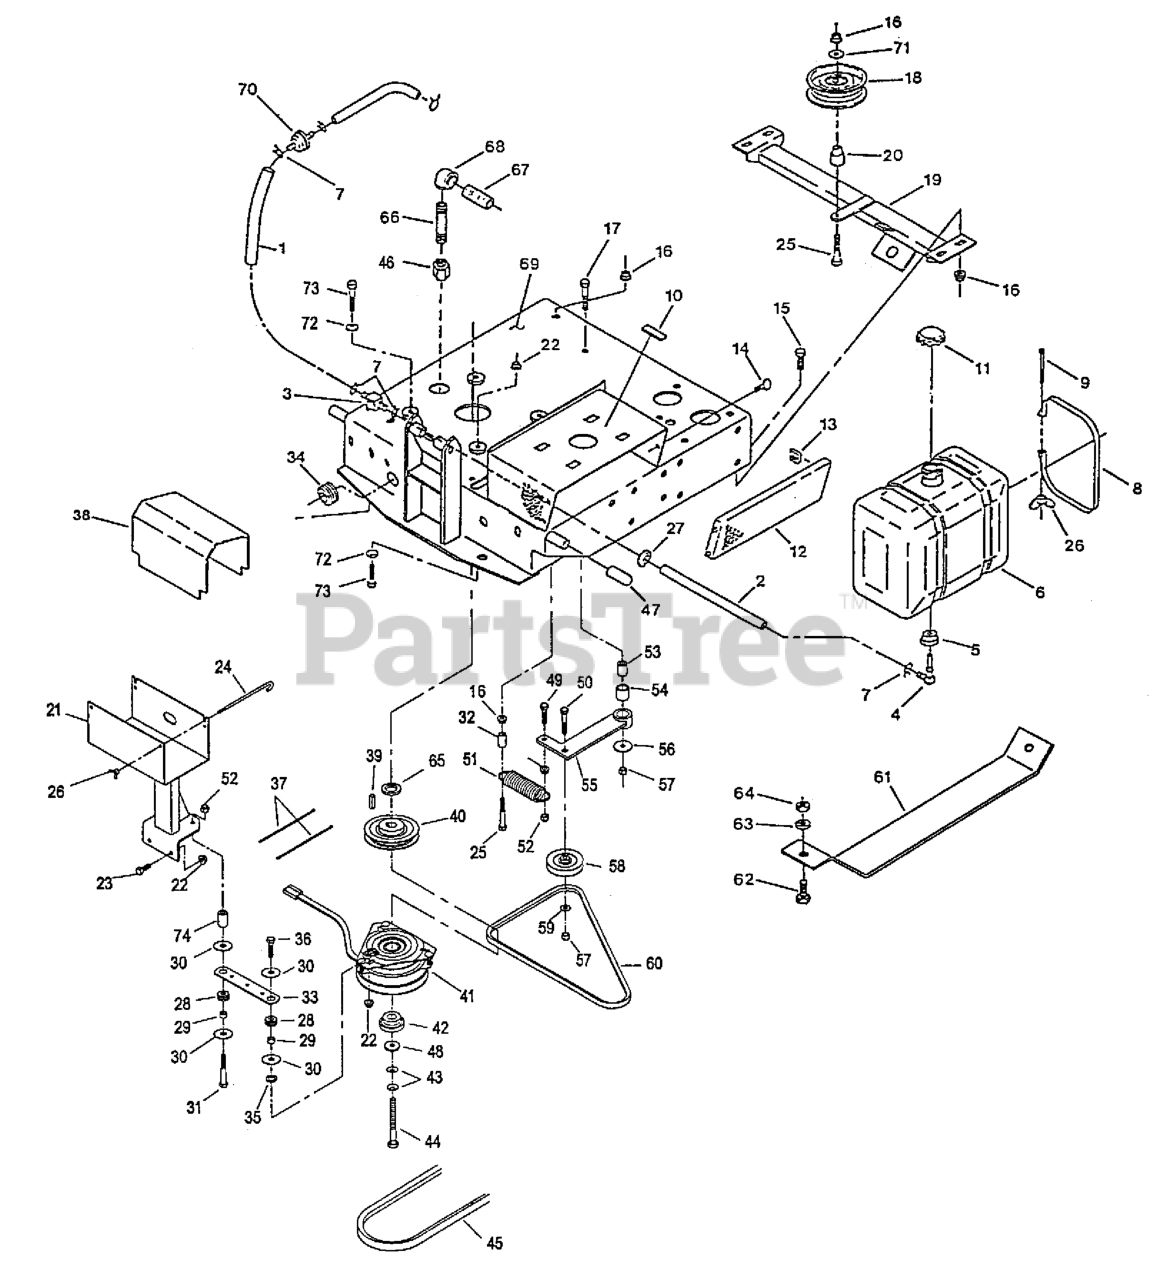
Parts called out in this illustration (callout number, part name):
1	HOSE-FUEL
3	VALVE-FUEL
4	ELBOW-TANK, FUEL
9	SCRW,MACH CRPH
10	PAD,PLASTIC TANK
11	CAP-FUEL
13	NUT,RETNR UTYP 1/4-20
14	SCREW,REGTHMB,
15	SCREW-HH
16	NUT-HHF, WHIZ
17	SCREW-HH
19	WLD,CROSSMEMBER
20	BUSHING,IDLER
21	WLD,BATTERY MOUNT
23	SCREW-HH
24	BOLT - HOLD DOWN
25	SCREW-HH
26	WINGNUT
27	GROMMET
28	GROMMET
31	SCREW-HH
33	STRAP-CLUTCH, BRAKE
34	GROMMET
35	WASHER-LOCK
36	SCREW-HH
37	TIE-PLASTIC
40	SHEAVE,4.25 OD A
42	BUSHING,CLUTCH KEEPER
43	WASHER-SPRING
44	SCREW-HH
45	BELT,DECK DRIVE
46	CAP-HEX
47	GRIP-LEVER, DRIVE
49	Bolt-Carriage 5/16-18 X 1 1/4
50	SCREW-CARR
51	SPRING,EXTENSION
52	NUT-LOCK, NI
53	BUSHING,STEEL
54	BUSHING,IDLER ARM
55	WLD,IDLER ARM HYDRO
57	NUT-LOCK, NI
58	IDLER,PULLEY
59	NUT-HEX
60	BELT,A TRANS DRIVE
61	PLATE-SKID
62	SCREW-HH
63	WASHER-LOCK
64	NUT-HH
67	NIPPLE,PIPE
68	ELBOW-90 DEG
70	Kohler Fuel Filter
71	WASHER-FLAT
72	WASHER-SPRING
73	SCREW-HH
74	Spacer
